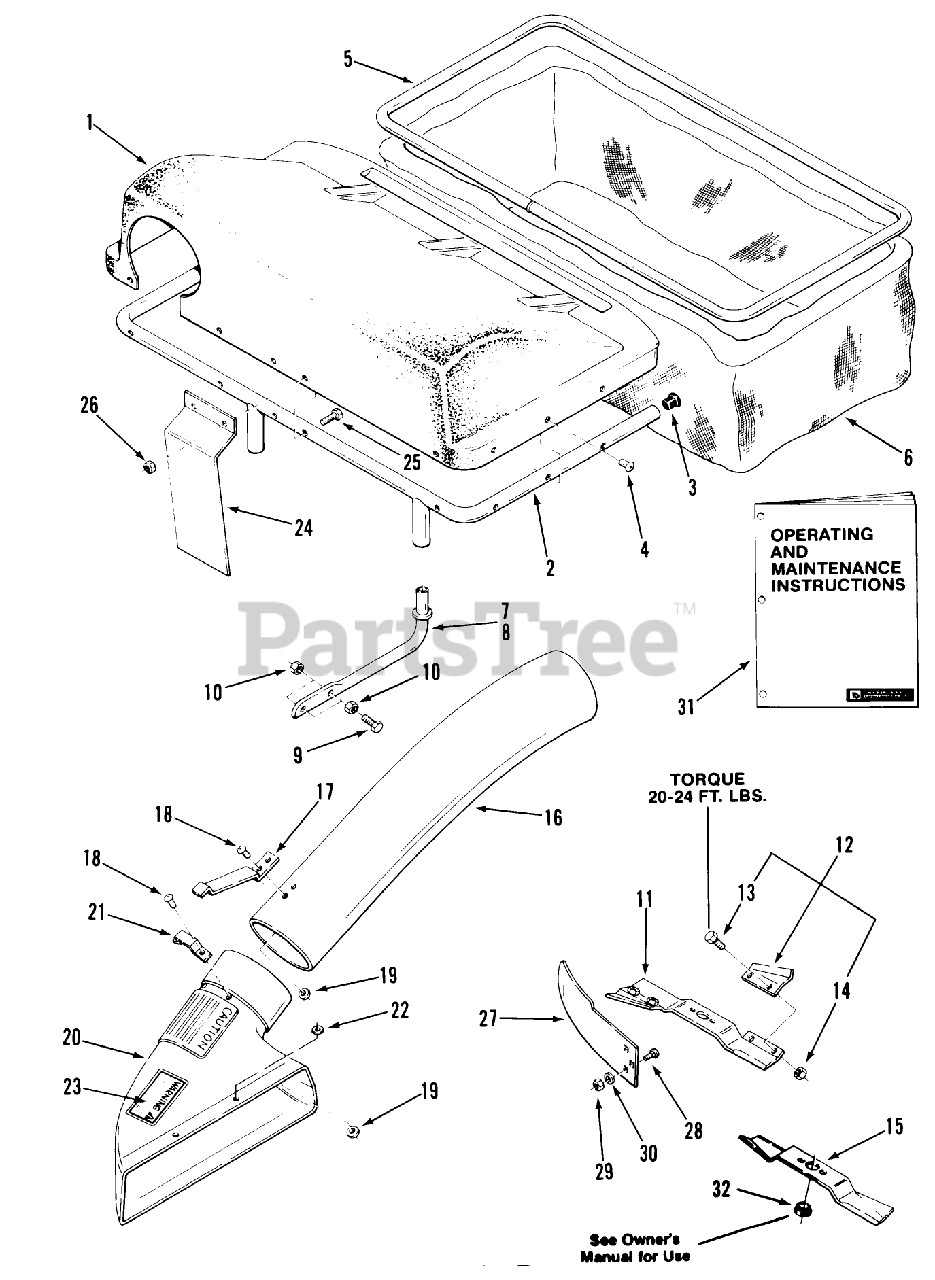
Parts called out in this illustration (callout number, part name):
5	FRAME-BAG *B
13	BOLT 5/16-18X5/8
14	NUT-HEX
15	BLADE 16.50
21	BRACKET
27	BAFFLE-DEFLECTOR *B
31	Operating and Maintenance Instructions
31	Operation and Maintenance Instructions
32	SPACER BLADE
